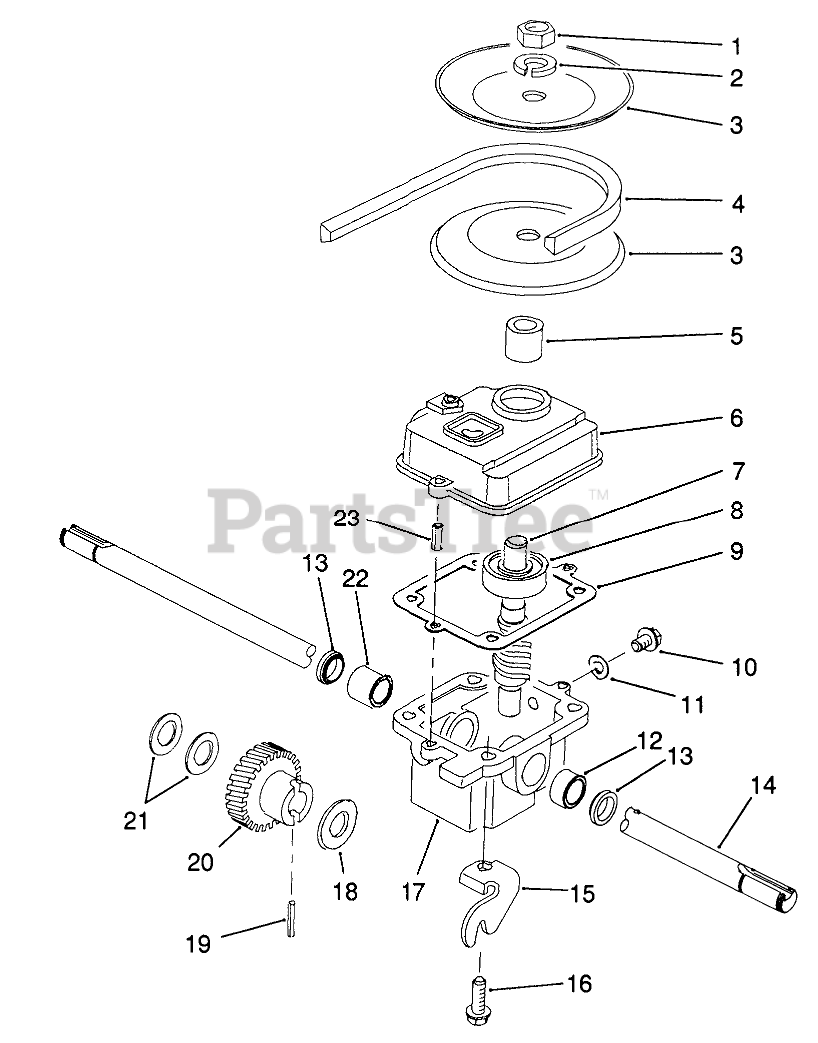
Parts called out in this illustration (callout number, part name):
1	NUT-JAM
2	WASHER-LOCK
3	PULLEY-DRIVEN HALF
4	V-BELT
5	SPACER - PULLEY
6	GEAR CASE COVER
7	SHAFT - WORM
8	BEARING
9	GASKET
10	NYLON SCREW
11	FILL PLUG GASKET
12	BUSHING
13	SEAL-OIL
14	OUTPUT SHAFT
15	TRACTION BRACKET
16	SCREW-HWHTF
17	GEAR CASE
18	THRUST WASHER
19	PIN-SPRING
20	GEAR - HELICAL
21	WASHER-PLAIN
22	BUSHING
23	3/16 X 1/2 ROLL PIN
